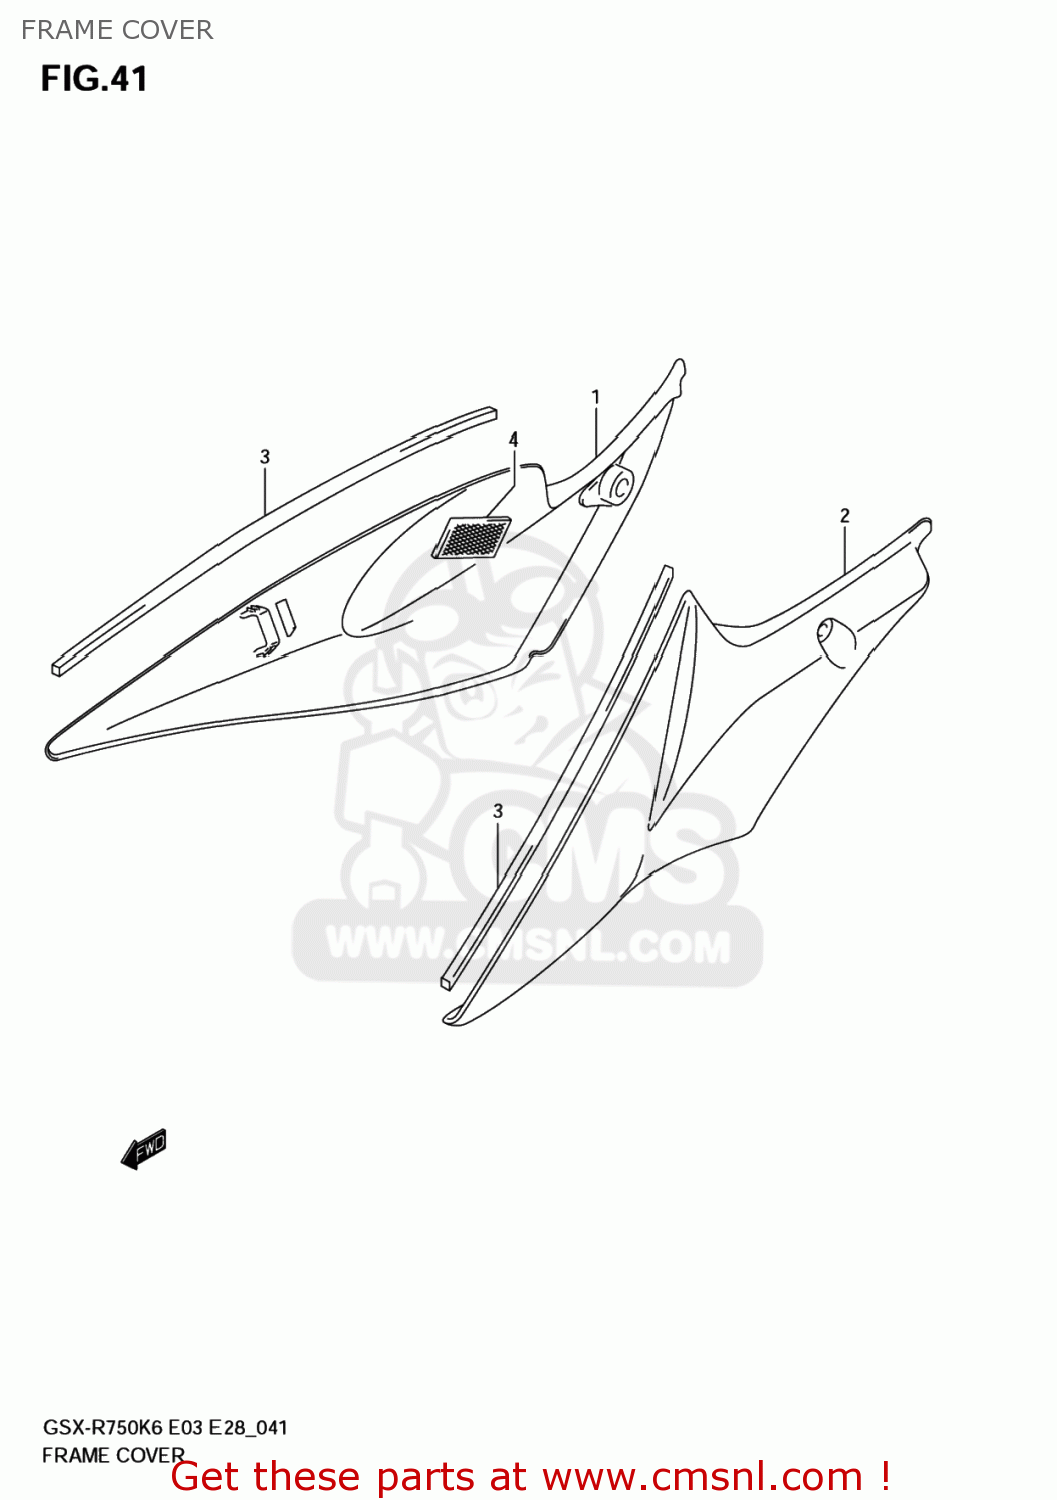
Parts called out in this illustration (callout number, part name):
1	COVER,FRAME,R(BLACK)
2	COVER,FRAME,L(BLACK)
3	CUSHION,FUEL TANK SIDE
4	FASTENER
